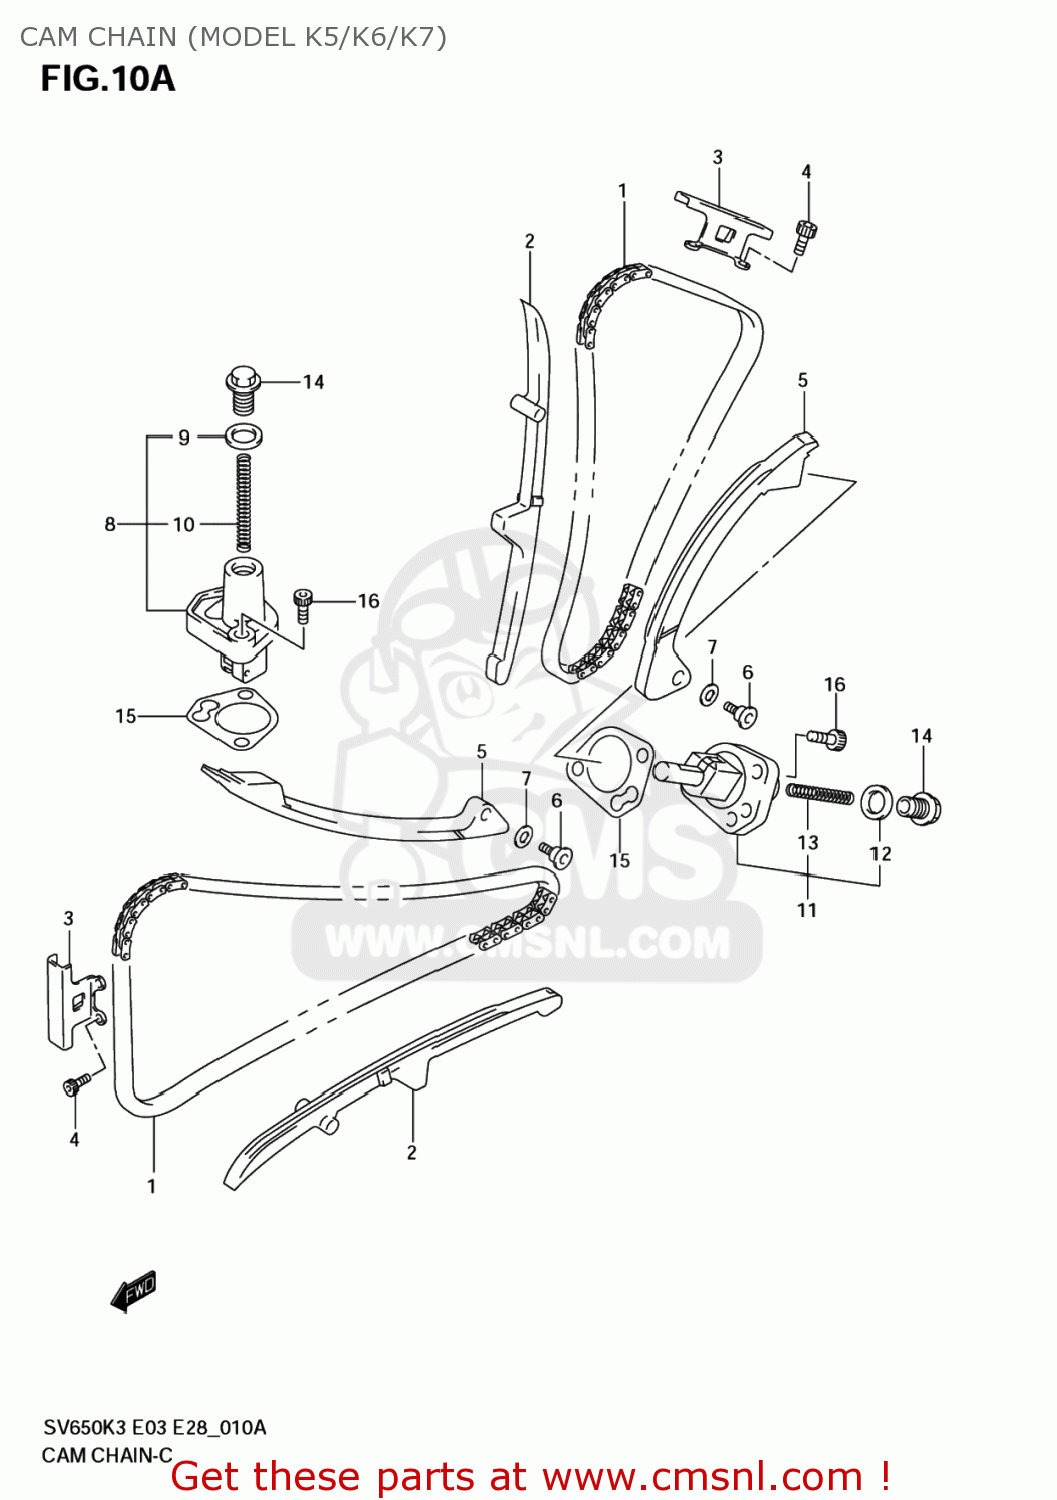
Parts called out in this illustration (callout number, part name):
1	CHAIN COMP,CAMSHAFT DRIVE
2	GUIDE,CAM CHAIN NO.1
3	GUIDE,CAM CHAIN NO.2
4	BOLT,STRANGER
5	TENSIONER,CAM CHAIN
6	BOLT,CAM CHAIN TENSIONER
7	WASHER
8	ADJUSTER ASSY,TENSIONER FR
9	GASKET,TENSIONER ADJUSTER (NAS)
10	SPRING
11	ADJUSTER ASSY,TENSIONER RR
12	GASKET,TENSIONER ADJUSTER (NAS)
13	SPRING
14	PLUG,TENSIONER ADJUSTER
15	GASKET,TENSIONER ADJUSTER (NAS)
16	BOLT,CL.COVER
